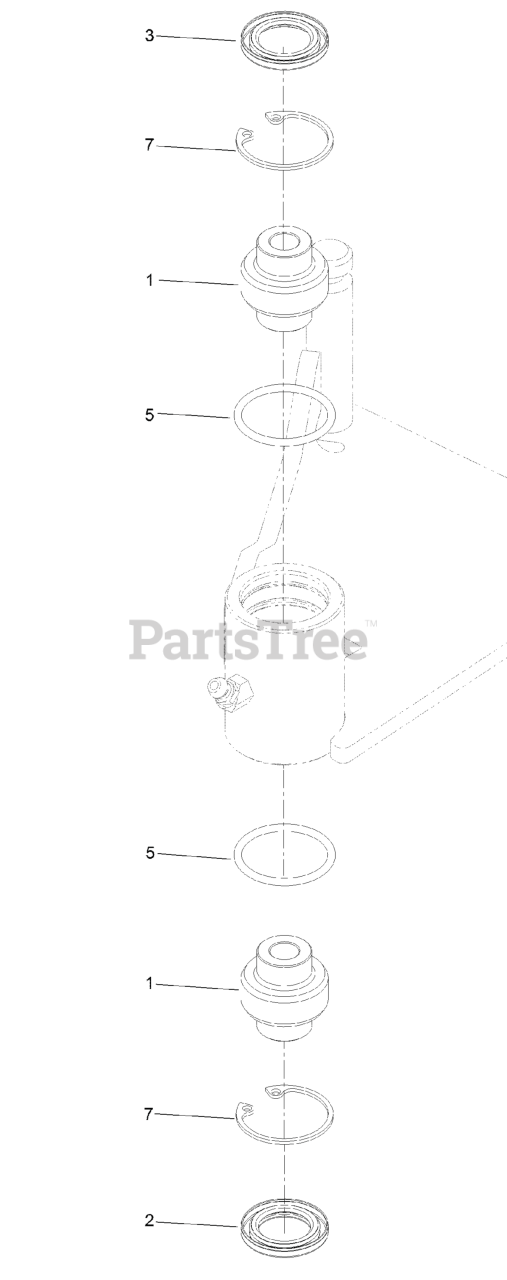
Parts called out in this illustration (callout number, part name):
1	BEARING-SPHERICAL
2	SEAL-LIP, DOUBLE
3	SEAL-LIP, SINGLE
7	RING-SNAP
